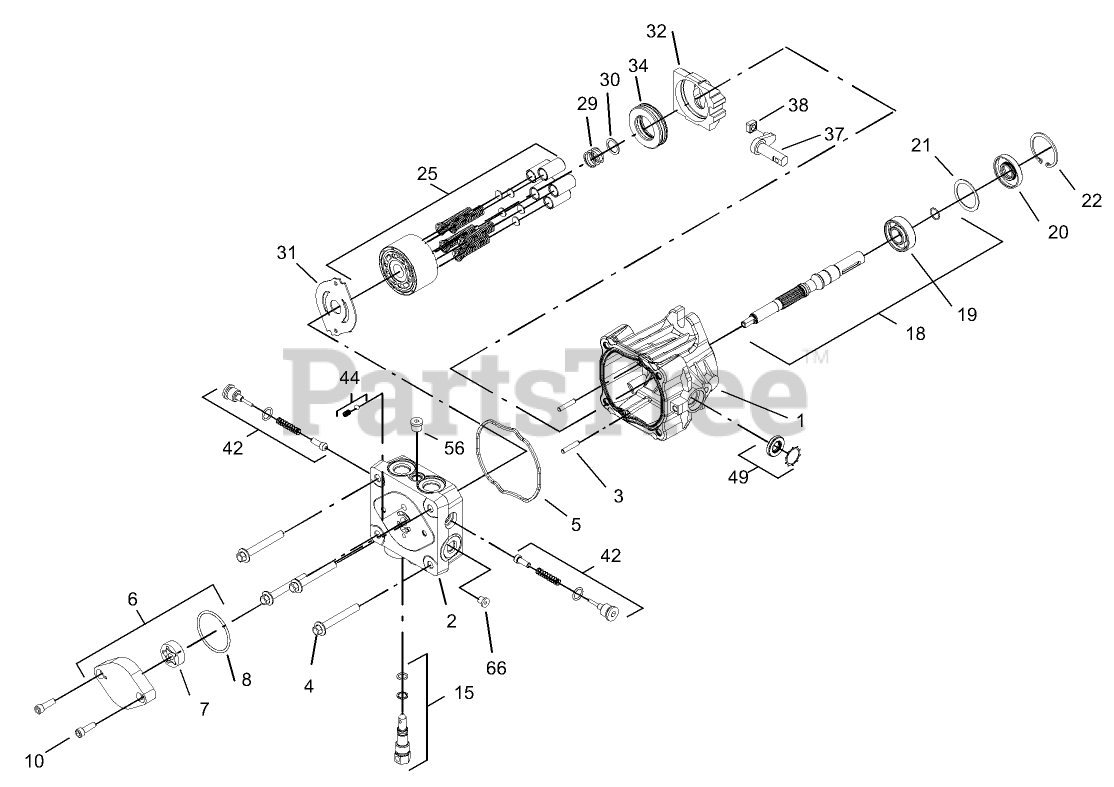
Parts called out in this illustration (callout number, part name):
1	HOUSING KIT
2	END CAP KIT (W/POPPETS)
3	PIN-HEADLESS, STRAIGHT
4	BOLT-HF
5	O-RING
6	CHARGE PUMP KIT
7	GEROTOR ASM
8	O-RING
10	SCREW-HSH
15	BYPASS VALVE KIT
18	INPUT SHAFT KIT
19	BEARING-BALL
20	SEAL-LIP
21	SPACER
22	RING-RETAINING
25	CYLINDER BLOCK ASM
29	SPRING-BLOCK
30	WASHER-THRUST
31	Plate-Valve
32	SWASHPLATE-VARIABLE
34	BEARING-THRUST
37	ARM-TRUNION
38	GUIDE-SLOT
42	VALVE-CHECK (W/POPPET)
44	CHARGE RELIEF VALVE KIT
49	TRUNNION SEAL / RETAINER KIT
56	PLUG-HSH
66	PLUG-HSH
